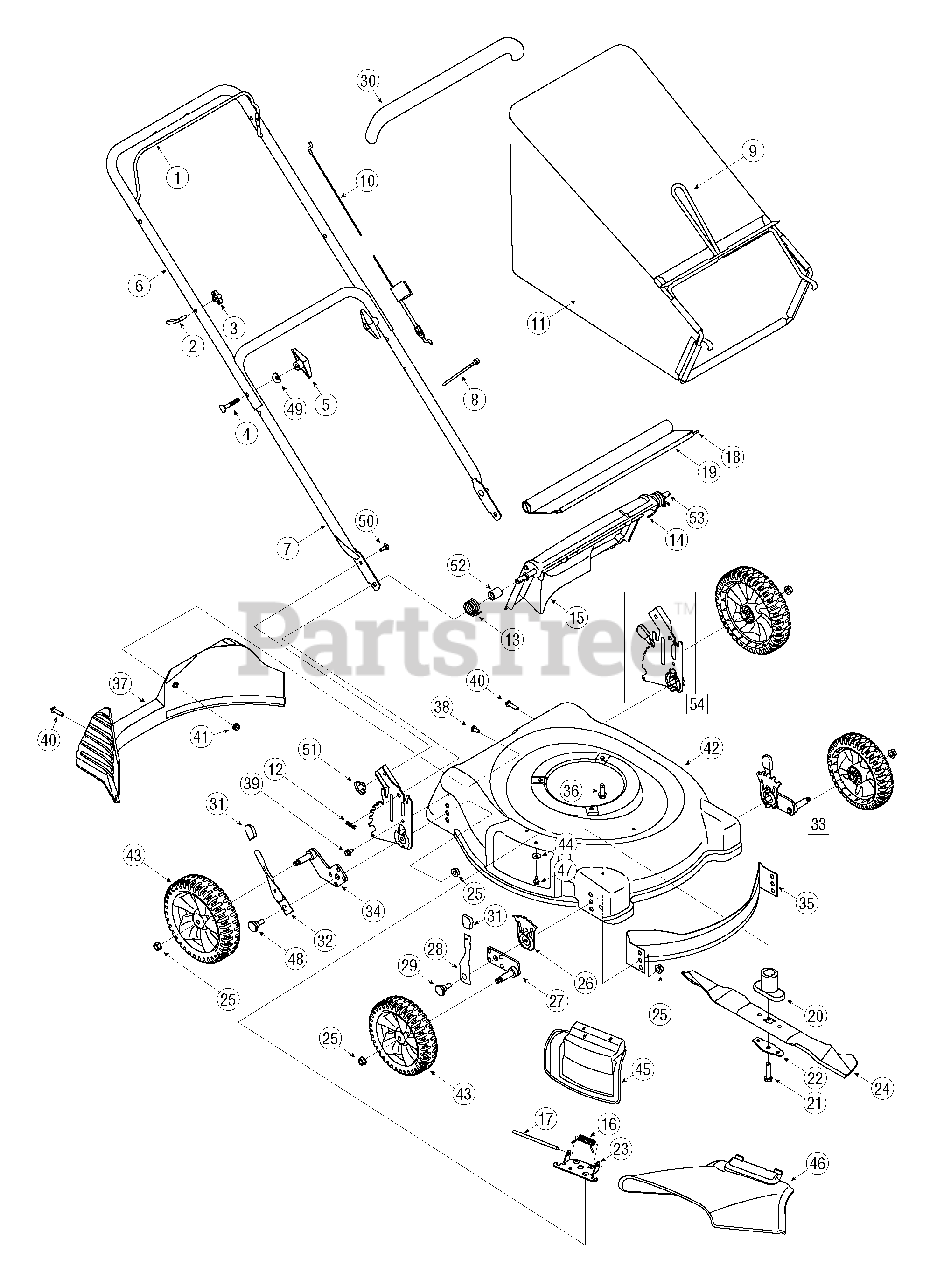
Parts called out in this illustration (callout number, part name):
2	Rope Guide
3	Handle Knob 1/4-20 Thd.
4	Curved Hd. Bolt 5/16-18 x 2"
5	Hand Knob
8	Cable Tie
10	Control Cable - 40"
11	Grass Bag
12	Int. Cotter Pin 5/16" Dia.
13	Door Spring - R.H.
14	Door Spring - L.H.
15	Rear Discharge Door
16	Torsion Spring
17	Hinge Pin
18	Wire Rod
20	Blade Adapter w/Star
21	Hex Bolt 3/8-24 x 2.5" Lg.
22	Blade Bell Support
23	Deflector Chute Adapter
24	21" Mulching Blade w/Star
25	Flange Nut 3/8-16 Thd.
26	Height Adj. Plate
27	Pivot Arm Assembly - LH
28	Front Spring Lever
29	Shld. Bolt.5" Dia. x.357"
30	Deluxe Bail Cover
31	Spring Lever Knob
32	Rear Spring Lever
33	Height Adj. Assy. Comp. - RH
34	Pivot Arm - RH
35	Front Baffle
36	Hex L-Wash.Scr. 3/8-16 x 1"
37	Rear Baffle
38	Screw, 1/4-20 x.500"
39	Hex Ind Wash. Scr. 1/4-20:.625
40	Screw, 1/4-15 x 1.250
41	Flange Lock Nut, 1/4-20
44	Bell Washer 1/4" I.D.
45	Hinged Mulching Plug
46	Side Chute Deflector
47	Hex Hd Self-Tp Scr. 1/4-20 x.5"
48	Shoulder Screw
49	Shoulder Washer
50	Hex Carriage Screw 1/4-20
51	Wing Nut
52	Spacer,.375OD x.50ID
53	Rear Door Pivot Rod
54	Rear Handle Bracket Assembly - LH
